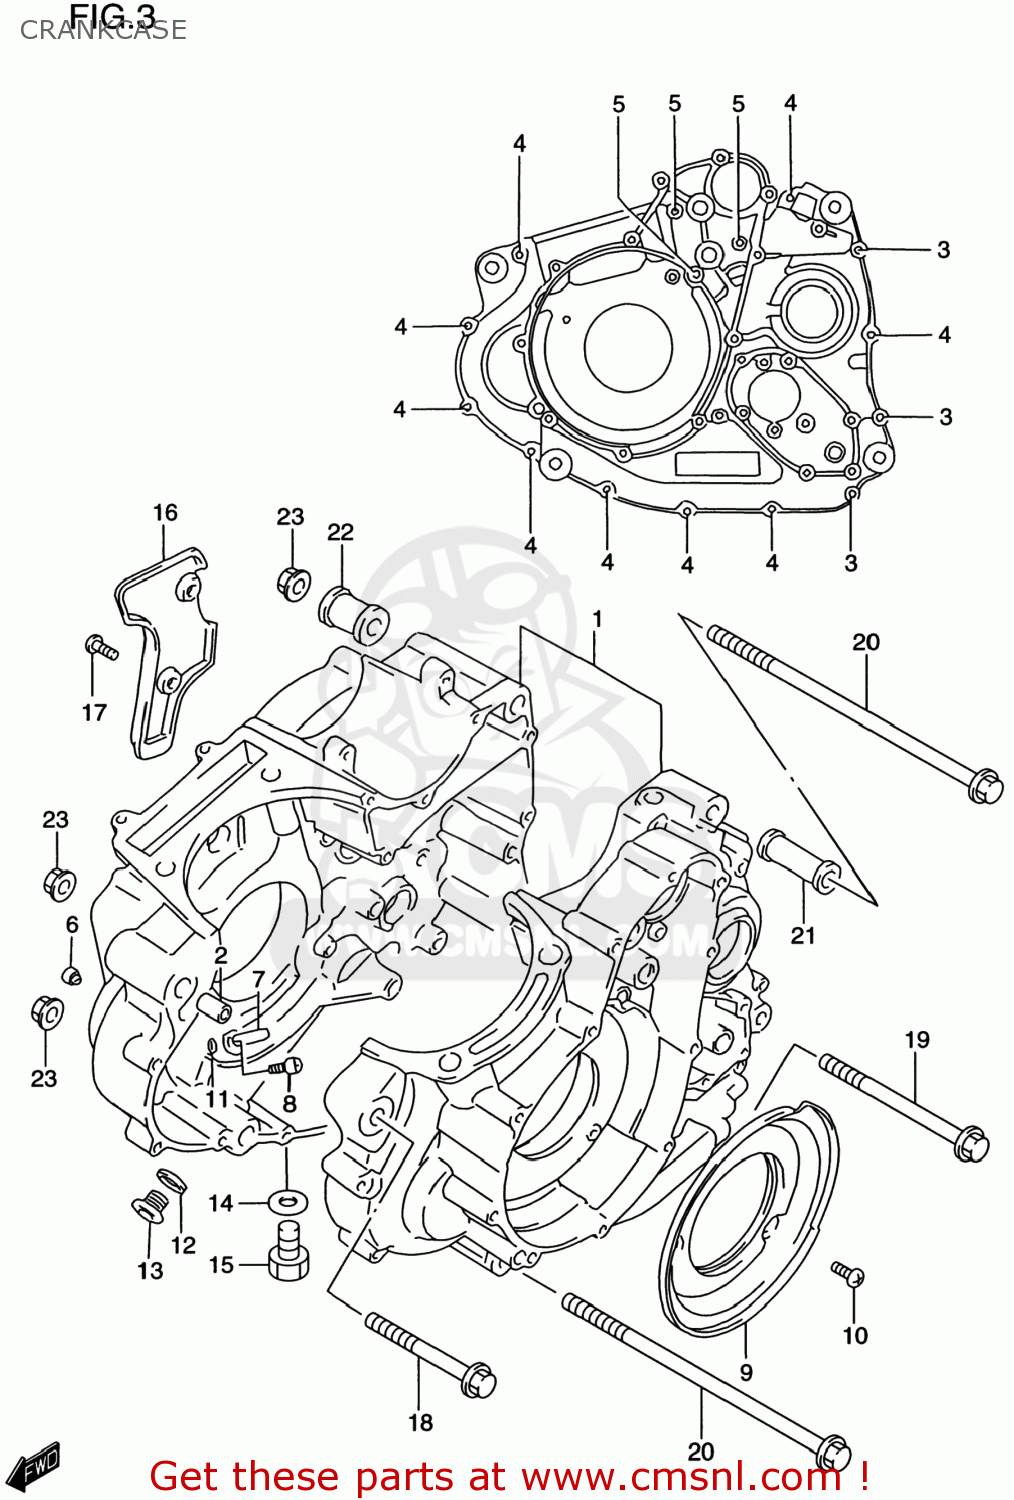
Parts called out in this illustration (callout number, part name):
1	CRANKCASE SET
2	PIN
3	BOLT
4	BOLT
5	BOLT
6	JET,OIL GALLERY
7	JET,PISTON COOLING
8	BOLT(6X12)
9	SEPARATOR,CRANKCASE OIL
10	SCREW
11	O RING(D:1.2,ID:4)
12	GASKET(13.8X18.8X4.8) (NAS)
13	PLUG,14X12
14	GASKET(13.8X18.8X4.8) (NAS)
15	PLUG
16	COVER,BREATHER
17	SCREW
18	BOLT(10X100)
19	BOLT(10X130)
20	BOLT(10X235)
21	SPACER,ENGINE MOUNT
22	SPACER,ENGINE MOUNT(L27)
23	NUT
